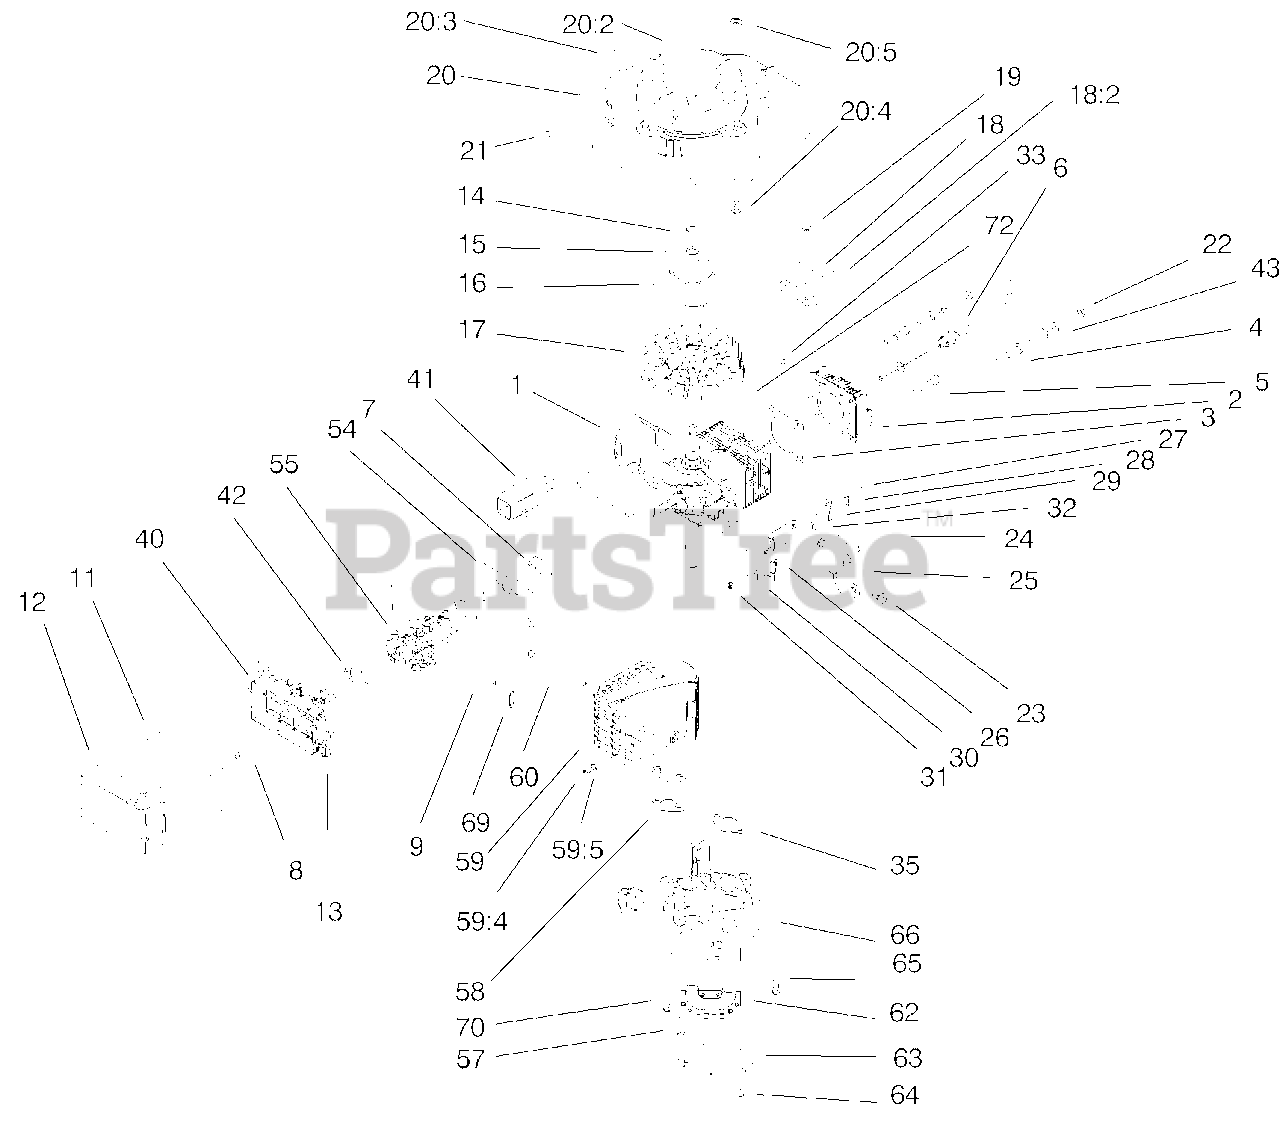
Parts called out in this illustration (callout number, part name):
1	SHORT BLOCK ASM
2	HEAD-CYLINDER
3	GASKET-HEAD
5	BOLT-HEAD
6	SPARK PLUG
7	GASKET-INTAKE
9	HOSE-PRIMER
11	FILTER-AIR
12	COVER-FILTER, AIR
13	RETAINER-COVER, FILTER
15	WASHER-LOCK
16	HUB-STARTER E COMM.
17	FLYWHEEL
18	Cd Ign
18:2	HT LEAD&COVER XEV
18:2	COVER & TERM. AY S
20	SHROUD-RECOIL
20:2	RECOIL ASM
20:4	SCREW-HWH
20:5	NUT-LOCK
21	SCREW-HH
23	SCREW-SHOULDER
24	SCREW-HWH
25	BRAKE PLATE AY EV
26	PLATE-BRAKE
27	RIVET-PLASTIC
28	STRAP-INSULATION
29	STRAP-GROUND
30	STOP-GROUND STRAP
32	LEAD WIRE-SWITCH, BRAKE
35	GASKET-EXHAUST
40	AIR BASE ASM
41	TUNNEL-INLET
42	GASKET-FILTER
43	WASHER-BELLEVILLE
54	SHIELD-CARB E
55	CARBURETOR ASM
59	MUFFLER & GUARD AY E
59:4	SCREW-HWH E
59:5	WASHER-LOCK, INTERNAL
60	BOLT-CONSOLE
62	PIPE-TRANSFER
63	COVER-MUFFLER E
64	SCREW-HH
65	SCREW-HH
66	PLATE-MOUNTING
69	HOSE-RETAINER
72	STRAP-TIE
